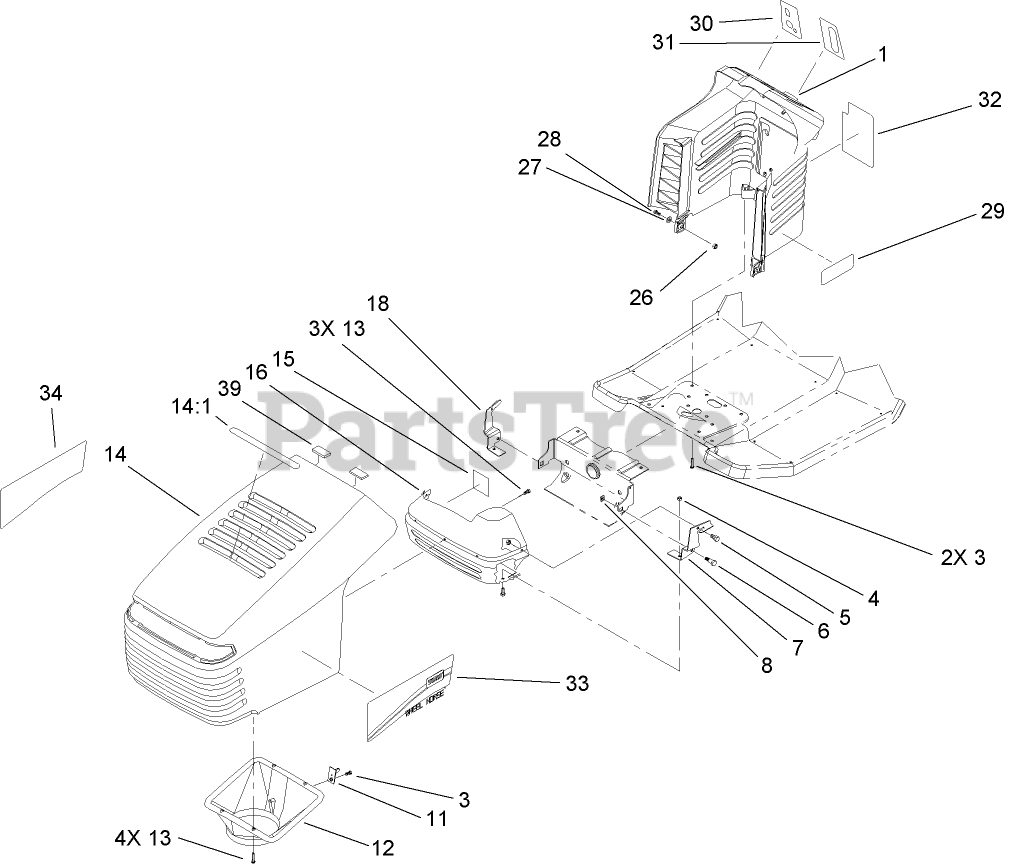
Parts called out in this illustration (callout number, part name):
1	TOWER-STEERING
3	SCREW-HWH
4	NUT-LOCK, NI
5	SCREW-HH
6	BOLT-SHOULDER
7	BRACKET-PIVOT, LH HOOD
8	NUT-RETAINER
11	LATCH-PIN
12	DUCT-AIR, HOOD
13	SCREW-PLASTITE
14	HOOD ASM
14:1	DECAL-AIR DUCT
15	PICK AS EACH
16	SHIELD-HEAT
18	BRACKET-PIVOT, RH HOOD
26	NUT-LOCK, NI
27	WASHER-PLAIN
28	SCREW-HH
29	DECAL-TOWER
30	DECAL-IGNITION/LIGHTS
31	DECAL-THROTTLE/CHOKE
32	DECAL-DANGER
33	DECAL-HOOD
34	DECAL-HOOD
39	FOAM-HOOD
